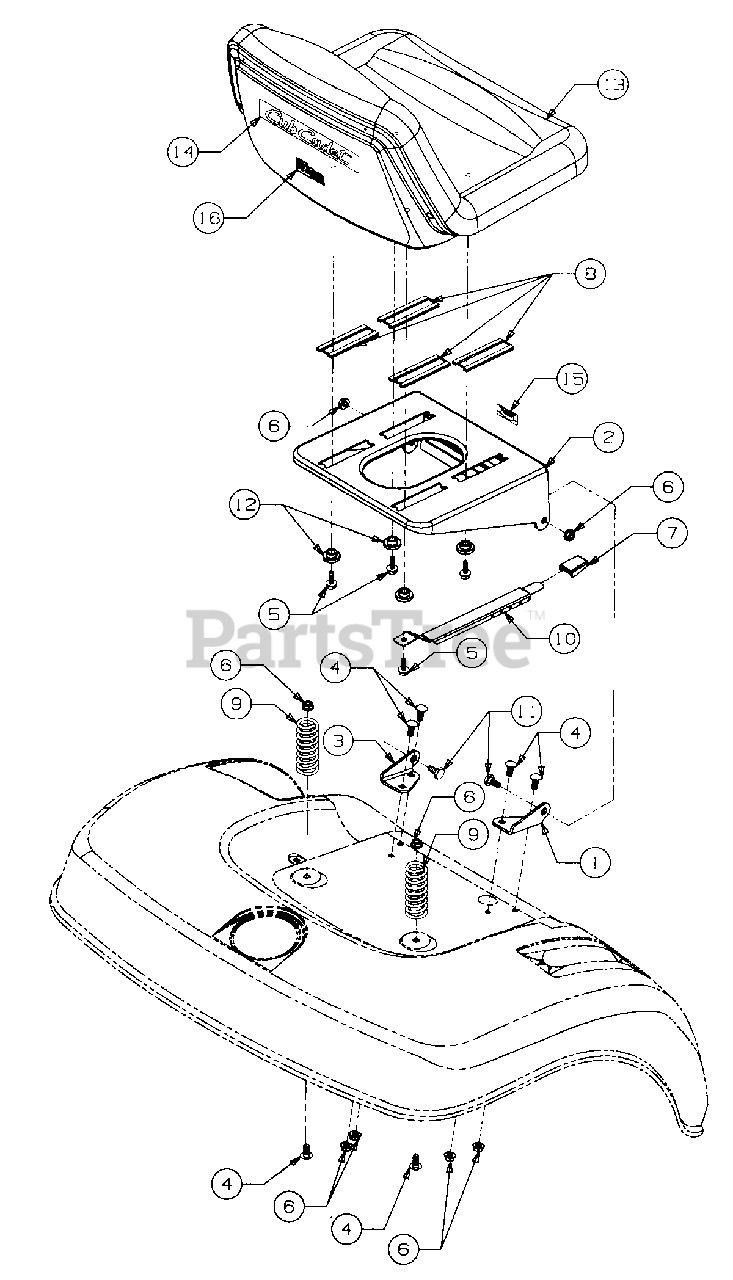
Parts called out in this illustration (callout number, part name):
5	Screw, Hex Wash Sf-Tapp 5/16-18 x .75 Lg
6	Nut, Hex Flange Top Lock 5/16-18
7	Knob, Seat Adjuster
8	Slide, Seat
9	Spring, Compression 1.9 OD x 2.4 Lg
10	Adjuster, Seat
11	Bolt, Shoulder
12	Spacer, Shoulder
13	Seat, Medium Back
14	Graphic, Seat Back Script
15	Graphic, Seat Adjuster
16	Graphic, Made in USA
